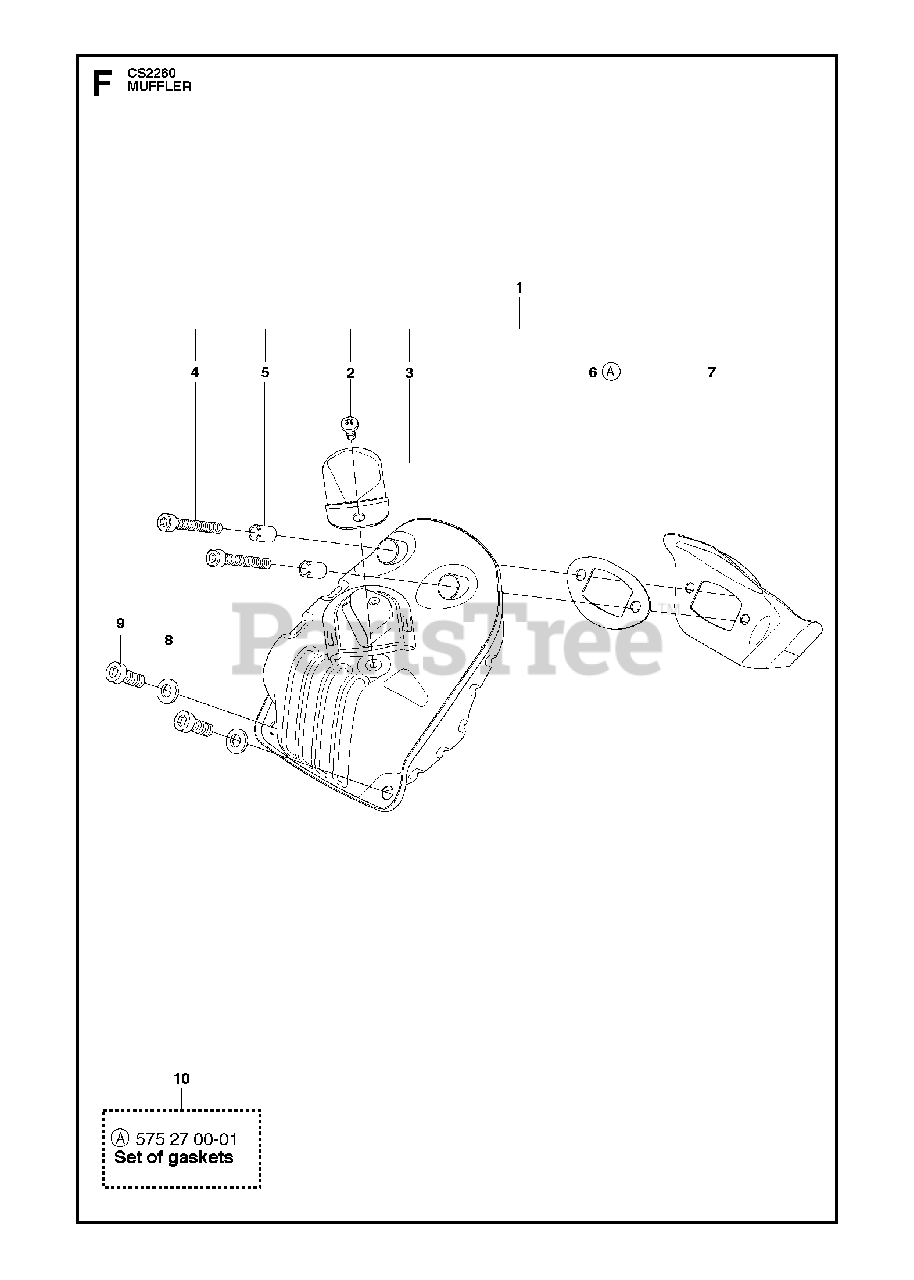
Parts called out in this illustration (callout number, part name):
1	MUFFLER KIT
2	SCREW
3	SPARK ARRESTER
4	SCREW
5	SLEEVE MUFFLER
6	GASKET MUFFLER
7	HEAT DEFLECTOR
10	GASKET KIT
